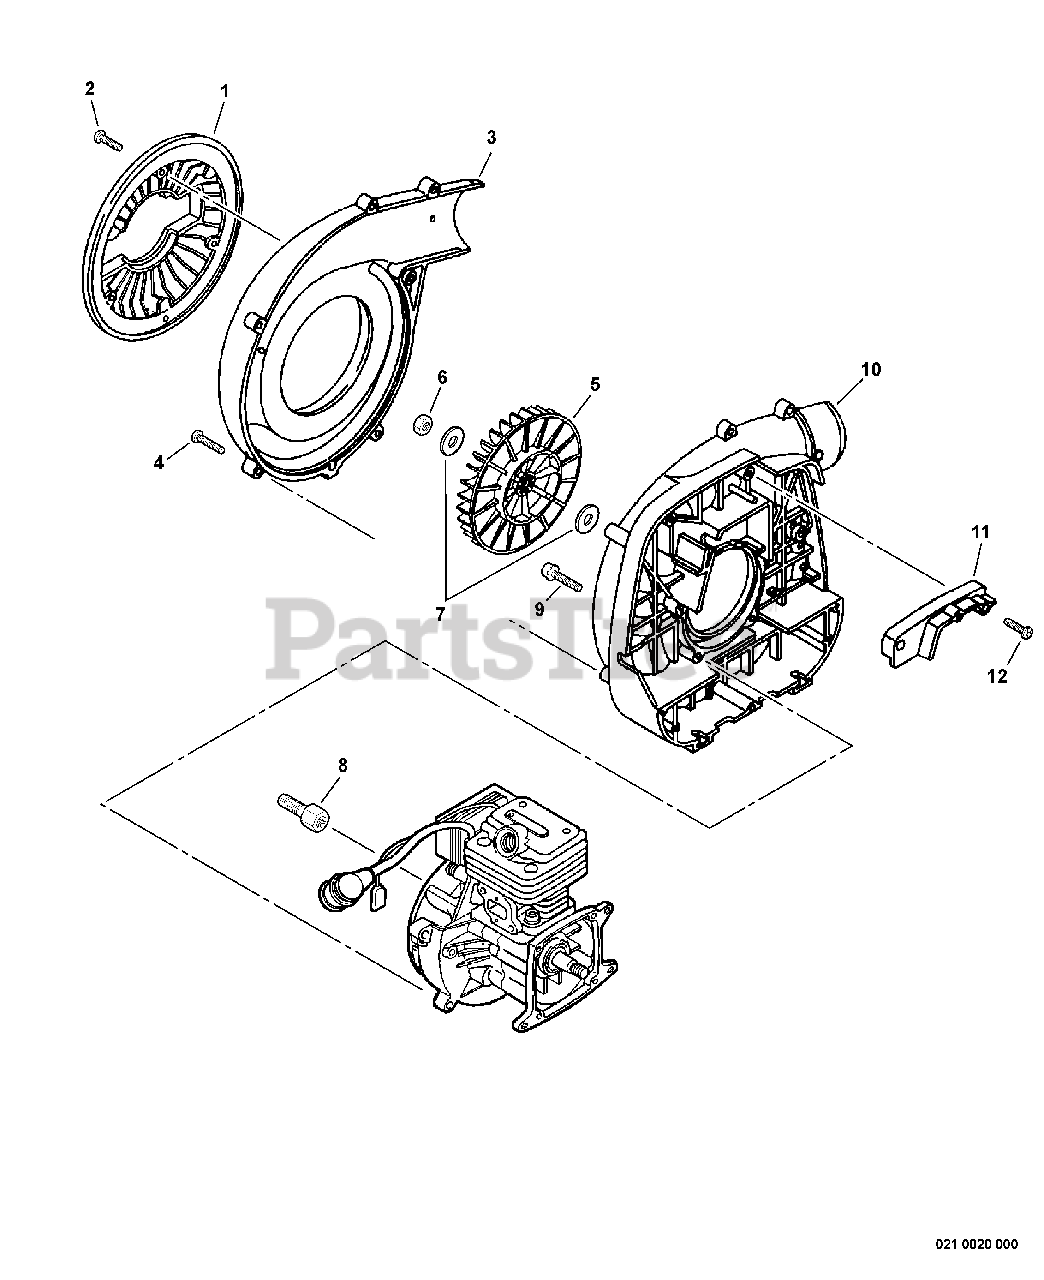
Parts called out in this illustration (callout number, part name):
1	GUARD, DEBRIS
2	SCREW - 5X16 -- TAPPING
3	COVER, FAN - OUTER
4	SCREW - 5X20 -- TAPPING
7	WASHER - 8
8	HUB, FAN
9	SCREW - 5X20
10	COVER, FAN - INNER
11	COVER, FAN CASE
12	SCREW - 5X16 -- TAPPING
